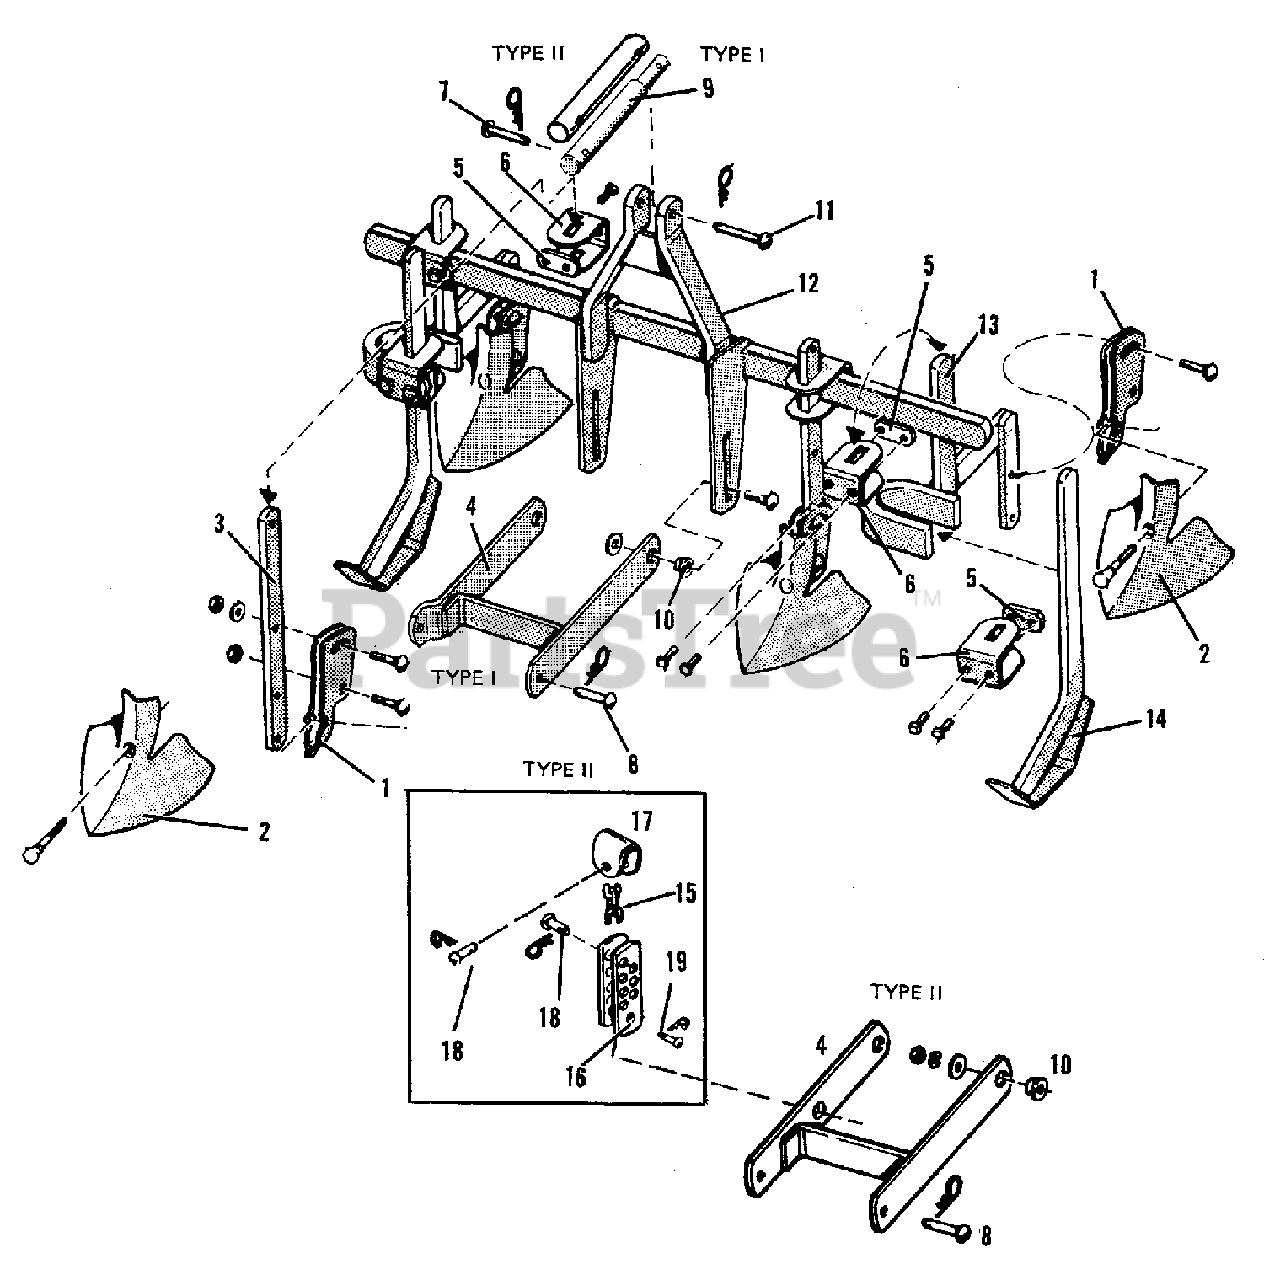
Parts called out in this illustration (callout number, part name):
1	HOLDER ASSEMBLY, Tool
1	BOLT, 3/8NC x 1-1/4, Carriage
1	WASHER, Plain, 3/8
1	NUT, 3/8NC
2	SWEEP, Universal
2	BOLT, Plow, 7/16NC x 2
2	WASHER, Plain, 7/16
2	NUT, 7/16NC
3	TOOL, Standard
4	ARM ASSEMBLY, (Type I)
4	ARM ASSEMBLY, (Type II)
4	BOLT, 7/16NC x 1-1/2
4	WASHER, 3/8
4	LOCKWASHER, 3/8
4	NUT, 7/16NC
5	NUT, Special
6	CLAMP, Shank
6	SETSCREW, 3/8NC x 1, Cup Point GR8
7	PIN, Quick
8	PIN, Round Head
8	PIN, Quick
9	BAR, Lift (Type I)
9	*ROD, Attaching (Type II)
11	PIN, Quick
12	BAR ASSEMBLY, Rear Tool
13	TOOL ASSEMBLY, Standard
14	SHOE ASSEMBLY, Weld
15	CHAIN, (Type II)
16	BRACKET, Depth Limit (Type II)
17	CLIP, Chain (Type II)
18	PIN, (Type II)
18	CLIP, Spring (Type II)
19	PIN, Pivot (Type II)
19	CLIP, Spring (Type II)
